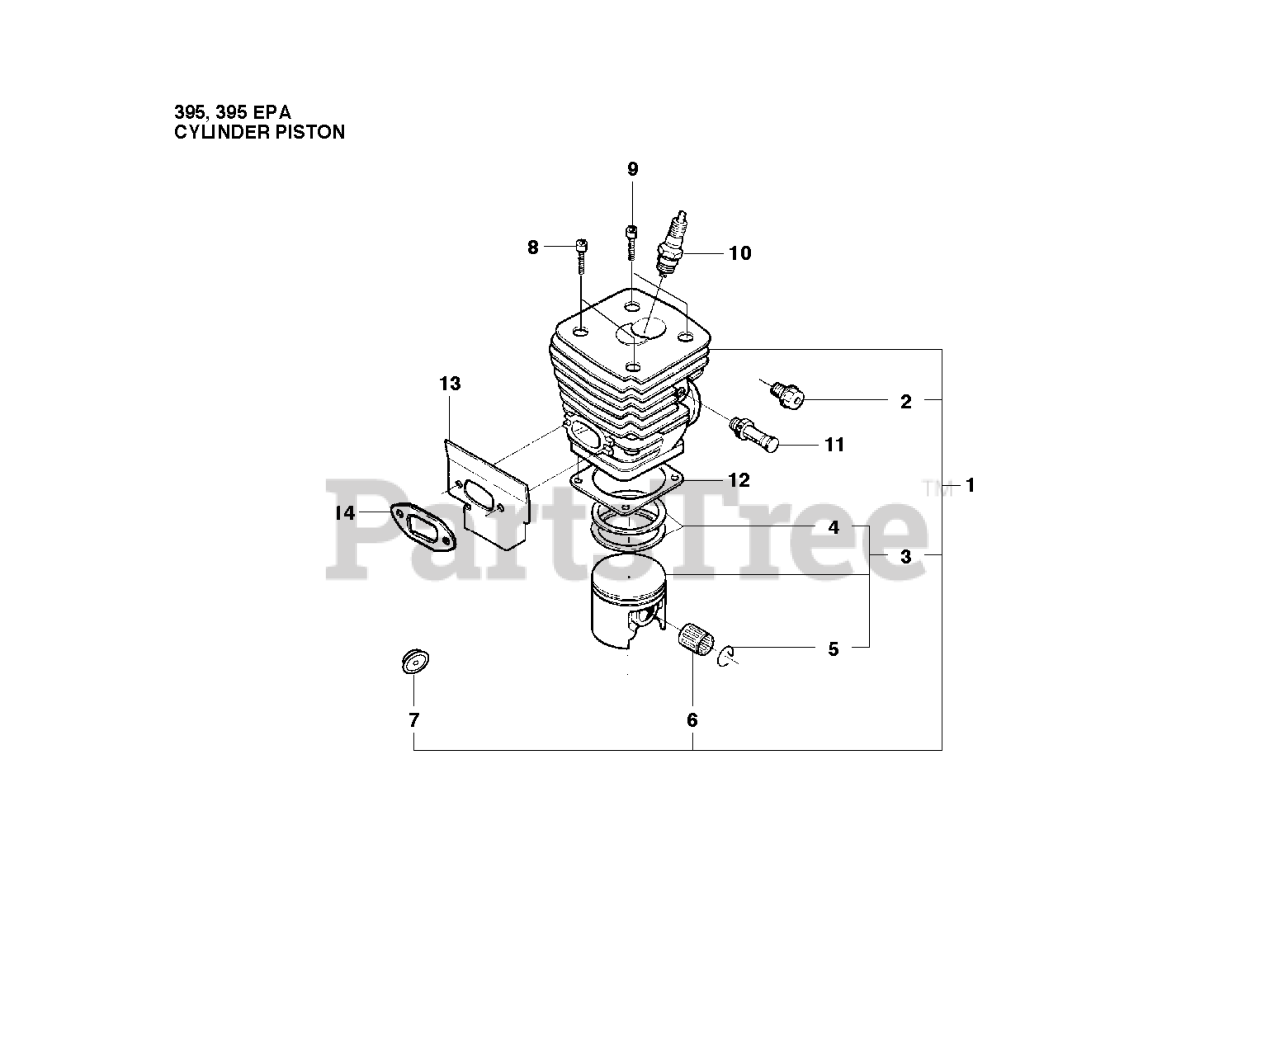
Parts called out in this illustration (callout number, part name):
2	CYLINDER PLUG
3	PISTON ASSY.
4	PISTON RING
6	SUPPORT BUSHING
10	SPARK PLUG RCJ6Y NLA
11	DECOMPRESSION VALVE
13	EXHAUST GASKET
